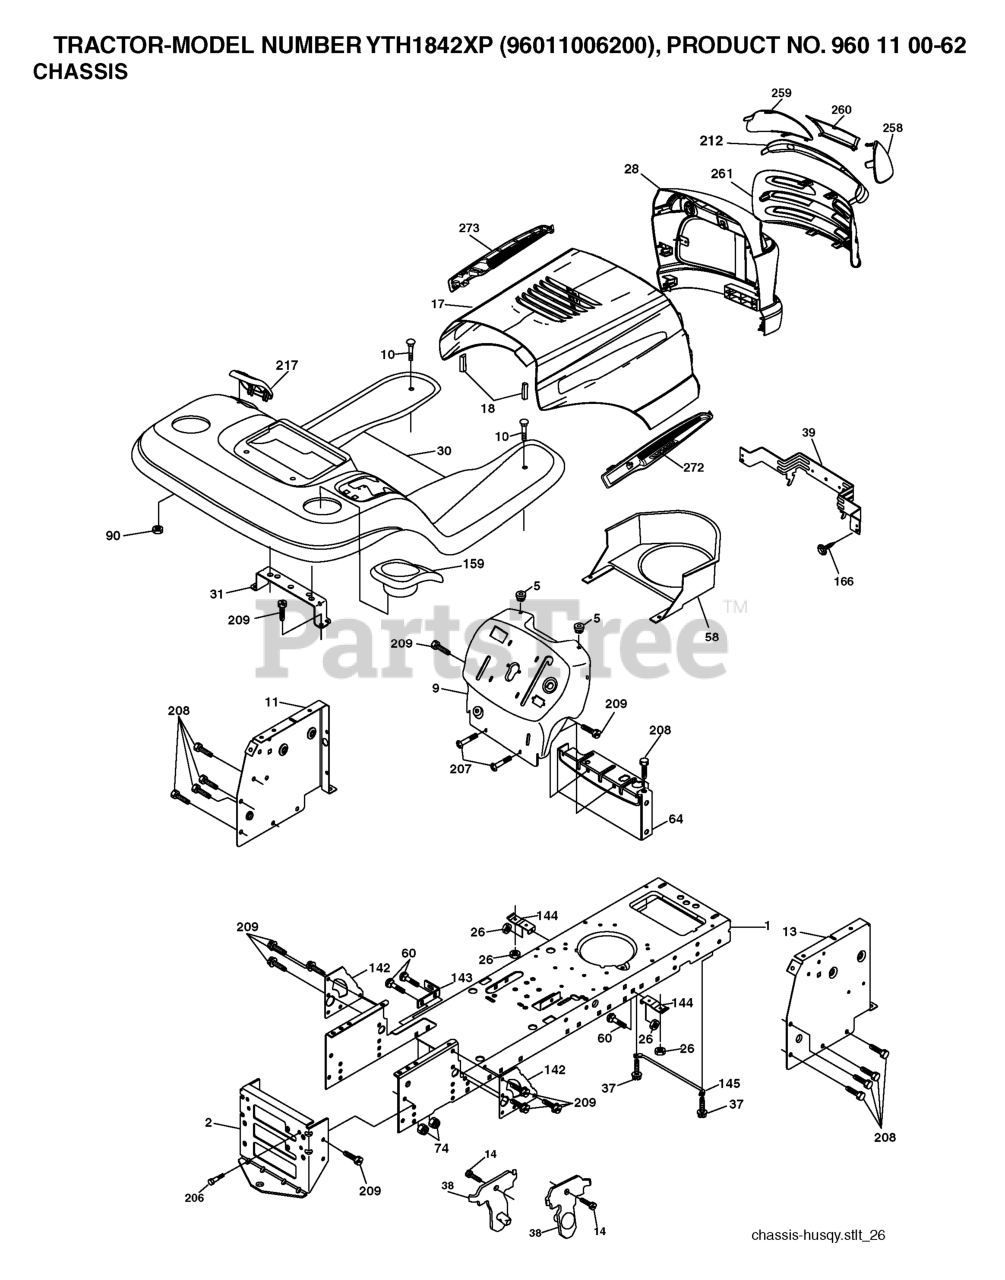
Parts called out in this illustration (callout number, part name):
1	CHASSIS STAMPING
2	DRAWBAR, 12GA
5	BUMPER.RUBBER.HOOD
10	BOLT D
11	PANEL.DASH.LH.LTX
13	PANEL ASM, DASH RH
14	SCREW LT
17	VENT.HOOD.LASER.III
18	BUMPER.HOOD.LARGE.1.75"
26	NUT
30	FENDER STL W/CUPHOLDER
31	BRACKET.SUPPORT.FENDER
37	Screw 5/16-18 x 1/2 Hex, Self Tapping 5/16-18 x 1/2
38	BRACKET.ASM.PIVOT.MOWER.REAR
39	BRACKET PIVOT LASER
60	Bolt - Rd. Hd. Sq. Neckiage 3/8 16 x 3/4
64	DASH LOWER
90	NUT.PUSH.3/16
142	PLATE REINFORCEMENT
143	BRACKET, SWAYBAR CHASSIS
144	BRKT, FOOT REST
145	ROD PIVOT CHASSIS/HOOD
159	GREY CUP HOLDER
166	SCREW
206	SHOULDER BOLT 5/16-18TT
207	SCREW, 5/16-18 X 1/2
208	SCREW 3/8-16X1/2
209	SCREW, 3/8-16X3/4
212	INSERT.LENS.REFLECTIVE
217	CONSOLE FUEL WINDOW
258	LENS LH
259	LENS LH
260	COVER.LENS.HUSQ.LASER
272	VENT.HOOD.LASER.
273	VENT.HOOD.LASER.
